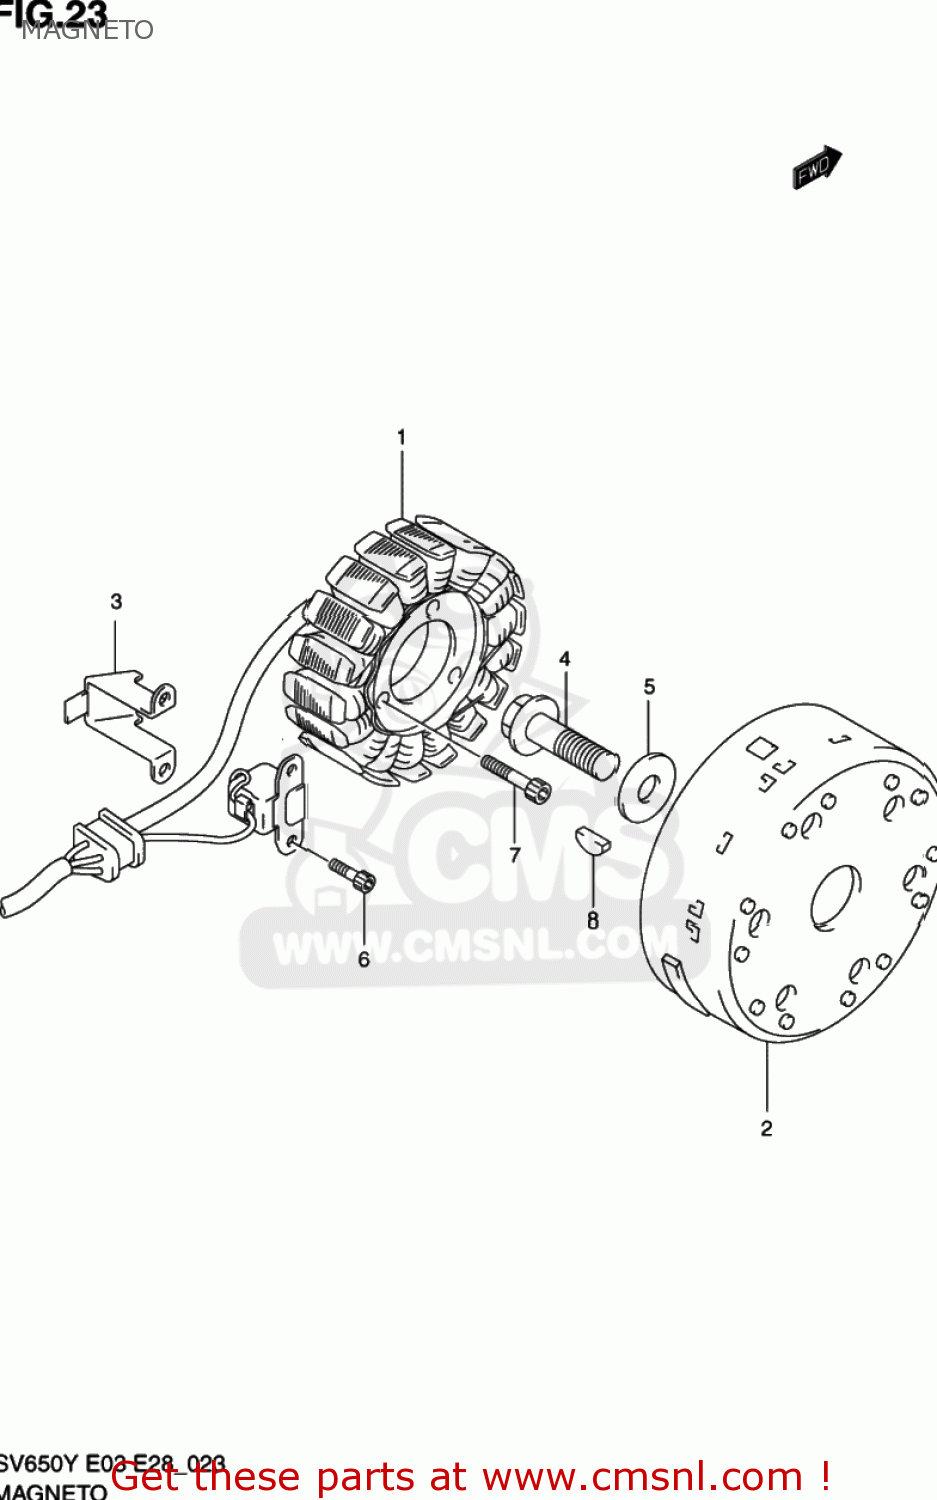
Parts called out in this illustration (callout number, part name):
1	STARTER ASSY
2	ROTOR ASSY
3	CLAMP,MAGNETO LEAD
4	BOLT(12X40)
5	WASHER(12X30X3)
6	BOLT
7	BOLT
8	KEY
